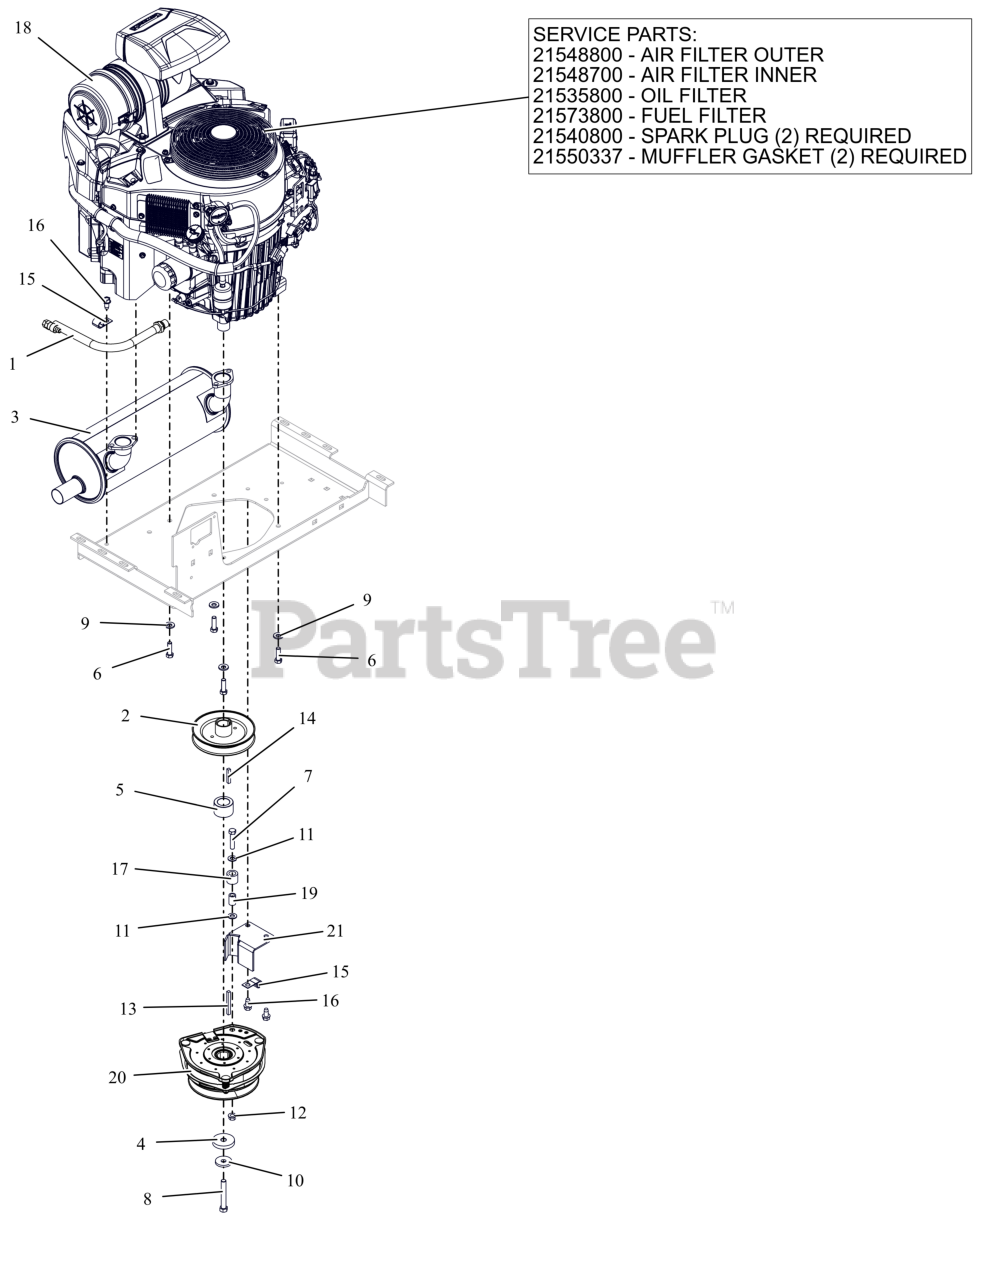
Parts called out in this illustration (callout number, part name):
1	HOSE, OIL DRAIN
2	WLDMT, TRANSAXLE DRIVE PULLEY
3	MUFFLER - 34HP KAWASAKI VERT.
4	SPACER, .474/.459X2.00X.350
5	SPCR, 1.125 x 1.750 x 1.147
6	BLT, HEX .38-16X1.25 G5 ZCC NT
7	BLT, HEX .38-16X1.75 G5 ZCC
8	BLT, HEX 0.4375-20X3 G8 ZCC NT
9	WASHER, 3/8" SPRING DISC
10	WASHER, 7/16" SPRING DISK
11	WSHR,FLT .406X.812X.065 ZCC
12	NUT-LK-CTR-FLG .375-16 GF ZCC
13	KEY-SQ .25 X 2.50 X .25 SAE
14	KEY-SQ .25 X 1.50 X .25 SAE
16	SCR,TAP .375-16X.75 HWH TR ZCC
17	BUMPER,RUBBER .62X1.0X.88 LG
18	ENGINE, KAWASAKI FX1000 EFI
19	BUSH.,S.391X.622X.950 ST
20	CLUTCH, OGURA GT3.5-AR04
21	WLDMT, CLUTCH STOP (BLACK)
